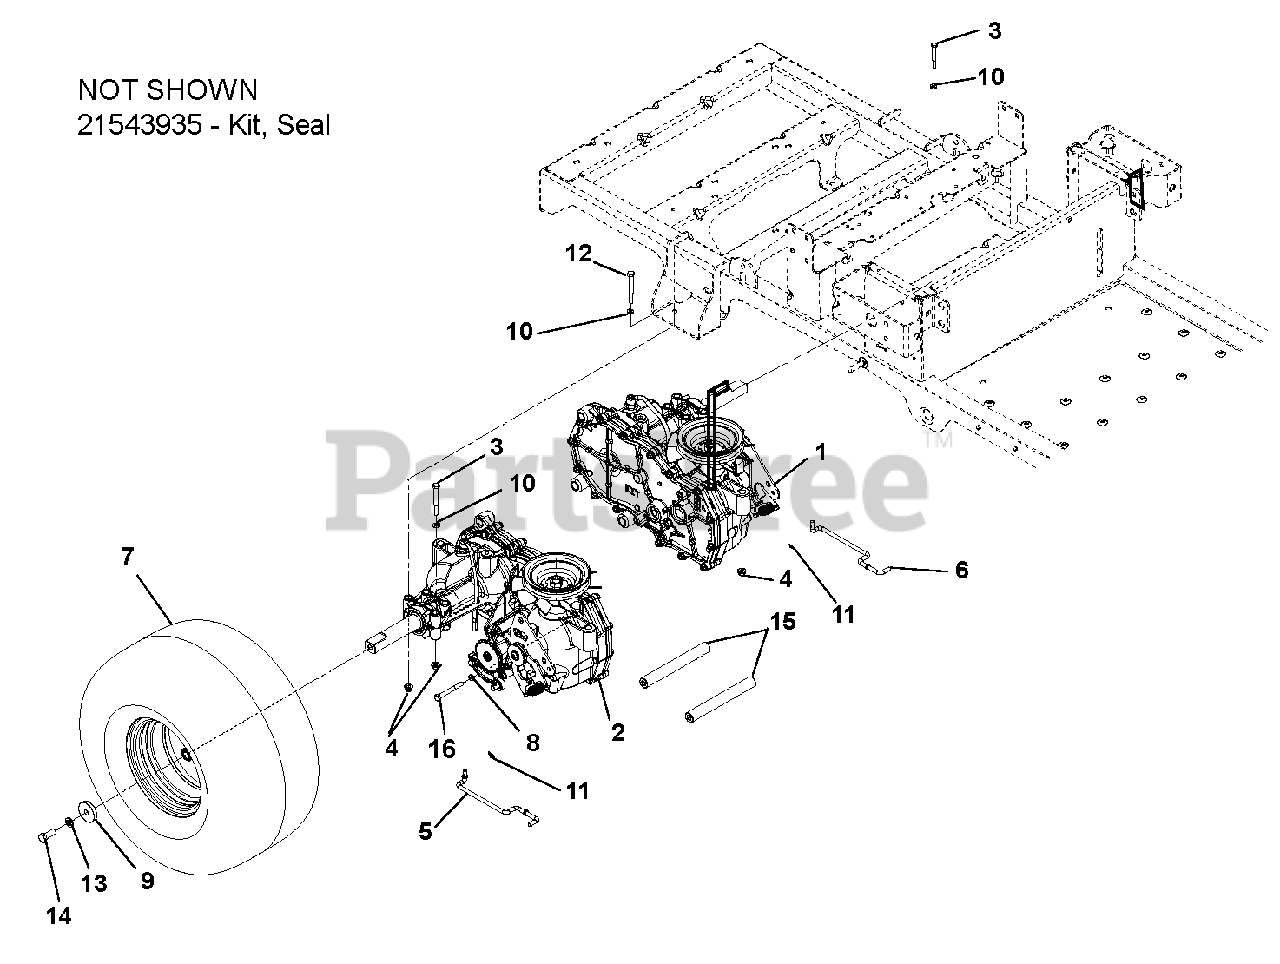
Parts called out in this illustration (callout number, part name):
1	Transaxle, Left Hand EZT D-Shaft (915146, 168)
2	Transaxle, Right Hand EZT D-Shaft (915146, 168)
3	Bolt, Hex .31-18 x 2.25
4	Nut 5/16-18 Flange Nyloc
5	Dump Valve, Right Hand
6	Dump Valve, Left Hand
7	Tire Assembly 18 x 6.5-8 2 Ply DSHAFT (915146, 168)
8	Washer, Flat Steel .406 x 1.00 x .188
9	Washer, Flat Steel .406 x 1.50 x .245
10	Washer, Flat Steel .38 x .875 x .083
11	Pin, Hair, Internal .06 x .18 x .77
12	Bolt, Hex .31-18 x 2.75
13	Washer, Locking .38 x .094 Regular
14	Bolt, Hex .38-16 x 1.00 YWZC EP30
15	Shaft, Transaxle Brace
16	BOLT, HEX .38-16 X 2.50
